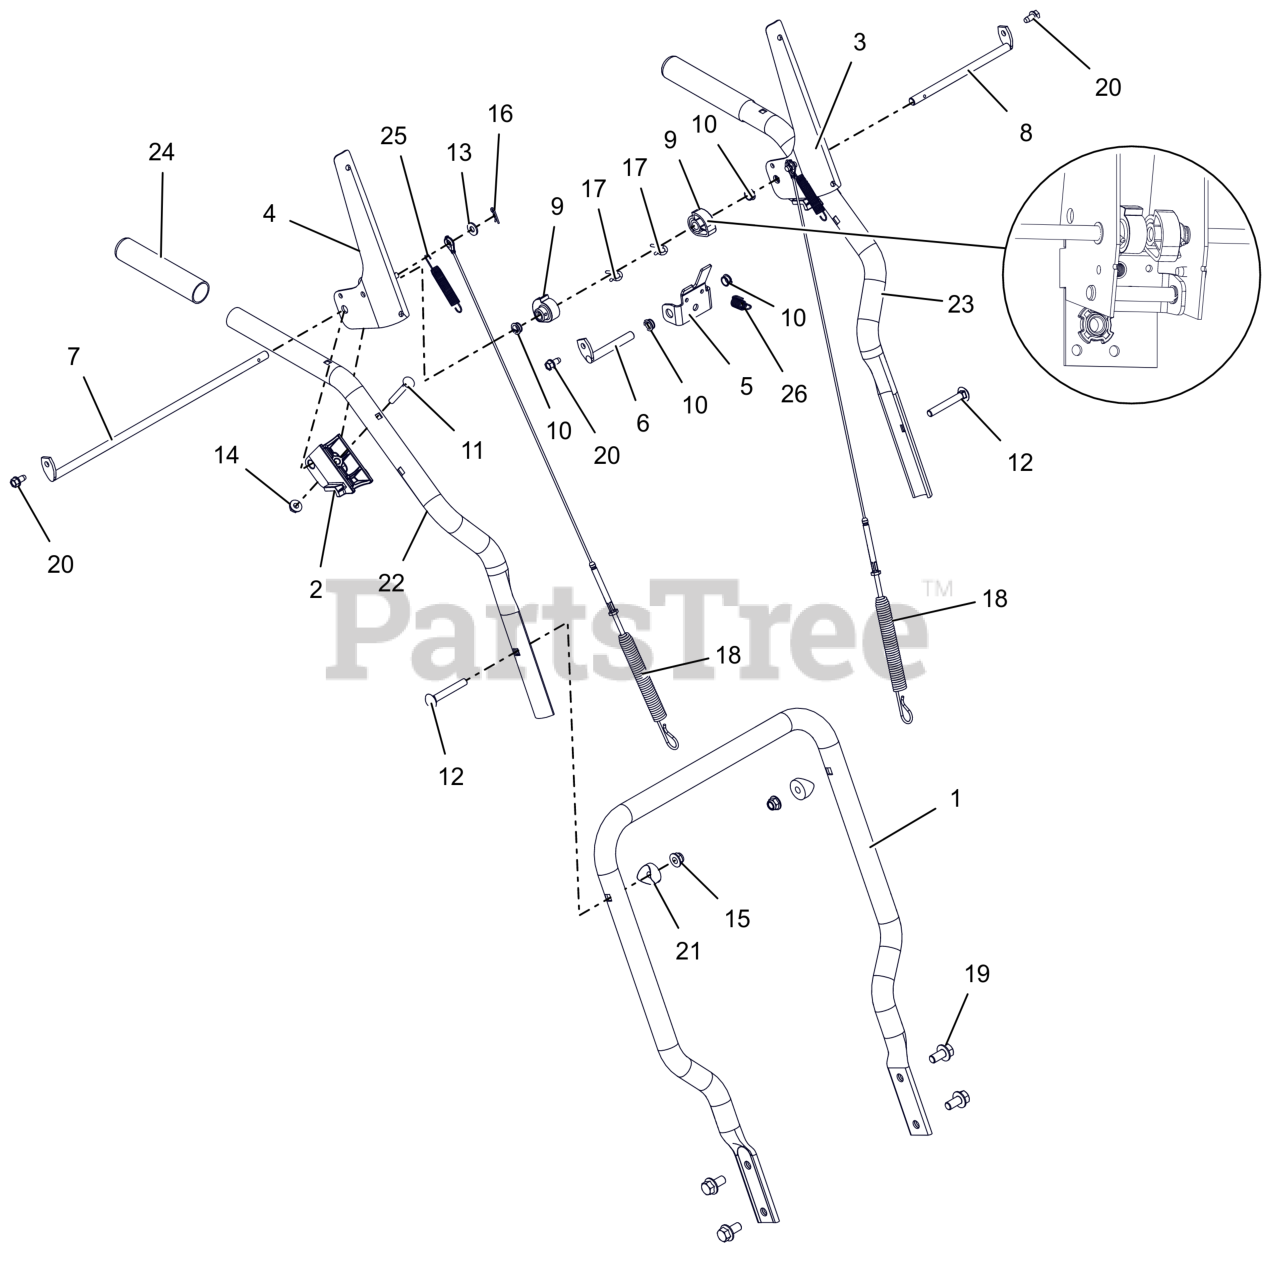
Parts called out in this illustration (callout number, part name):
1	HANDLEBAR, LOWER COMPACT (BLACK)
2	BLOCK, CLUTCH PADDLE
3	LEVER, CLUTCH-LH
4	LEVER, CLUTCH-RH
5	BRACKET, INTERLOCK ARM
6	ROD, PIVOT - INTERLOCK
7	ROD, PADDLE MOUNT - LONG
8	ROD, PADDLE MOUNT - SHORT
9	CAM, INTERLOCK
10	BUSHING, POLYLINER-.38 SNAPIN
11	BLT-RDHDXLSQNK .25-20X2.0 G5YZ
12	BLT, RHSN .31-18X2.25 G5 ZCC
13	WSHR,FLT .281X.625X.065 ZCC
14	NUT-LK-TOP-FLG .250-20 GF ZCC
15	NUT,LK-NYL-FLG .31-18 G5ZC120
16	PIN, HAIR #178 .06X.77 ZCC
17	PIN, SPRING CLIP
18	CABLE, AUGER & UPPER TRACTION
20	SCR-TAP .25-20X.50 HWH ZCC
21	SPACER, HANDLEBAR
22	HANDLEBAR, UPPER - RH (BLACK)
23	HANDLEBAR, UPPER - LH (BLACK)
24	GRIP,HANDLE-GRAY
25	SPRING, EXTENSION
26	SPRING-EXT .047X.438X1.45
